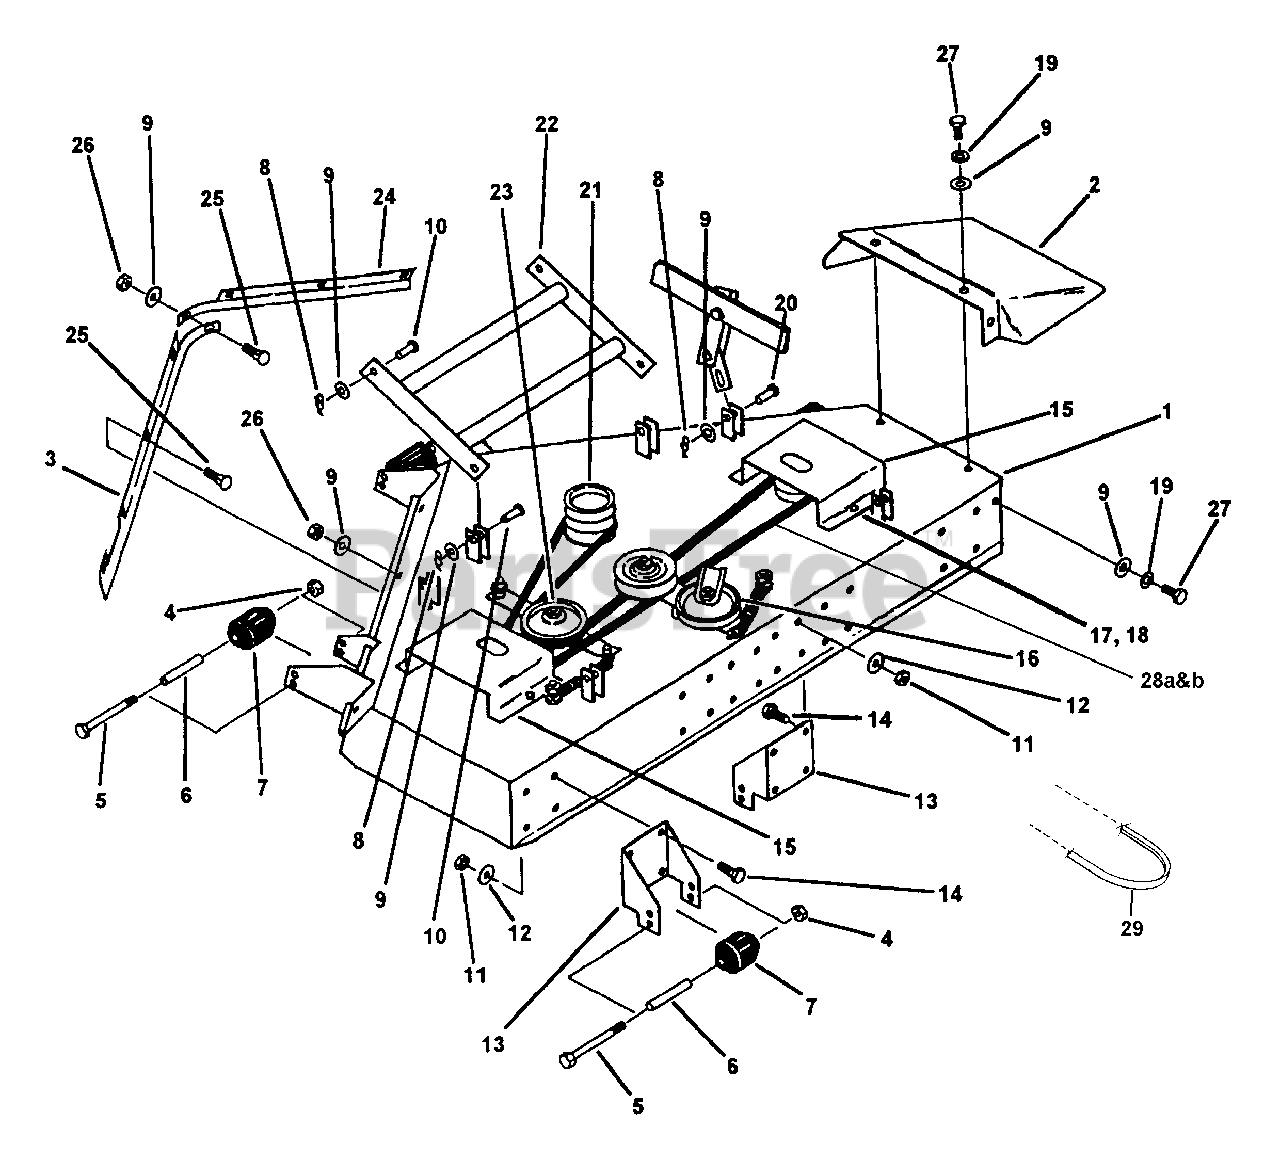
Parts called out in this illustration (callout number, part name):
1	DECK WLDT. 42"
2	DECK CHUTE ASS-Y, 42"
3	LIP BAFFLE, 42" L.H.
4	LOCKNUT, 3/8-16, .218 THICK
5	BOLT, 3/8-16 X 4-1/2" GR. 5
6	ROLLER SPACER BUSHING
7	ROLLER
8	COTTER RUE RING, 5/16-3/8 PIN
9	WASHER FLAT STD. 5/16"
10	CLEVIS PIN, 5/16 X 1-1/4" LONG
11	NUT, 3/8-16 NYLOC
12	WASHER, FLAT STD. 3/8"
13	REAR ANTISCALPER BRACKET
14	BOLT, 3/8-16 X 7/8" GR. 5
15	PULLEY COVER, LOW HEIGHT
16	DOUBLE IDLER ASSEMBLY
17	BOLT, 1/4-20 X 3/4" GR. 5
18	LOCKWASHER, 1/4" SPLIT SPRING
19	LOCKWASHER, 5/16" SPLIT SPRING
20	CLEVIS PIN, 5/16 X 1-1/2" LONG
21	SPINDLE ASSEMBLY
22	DRAG BAR WELDMENT
23	SINGLE IDLER PARTS
24	LIP BAFFLE, R.H.
25	BOLT, 5/16-18 X 3/4" CARRIAGE
26	NUT, 5/16-18 NYLOC
27	BOLT, 5/16-18 X 3/4" GR. 5
28A	42" DECK CROSS BELT, AP89
28B	48" DECK CROSS BELT, AP100
29	ENGINE TO DECK BELT, BP-82
